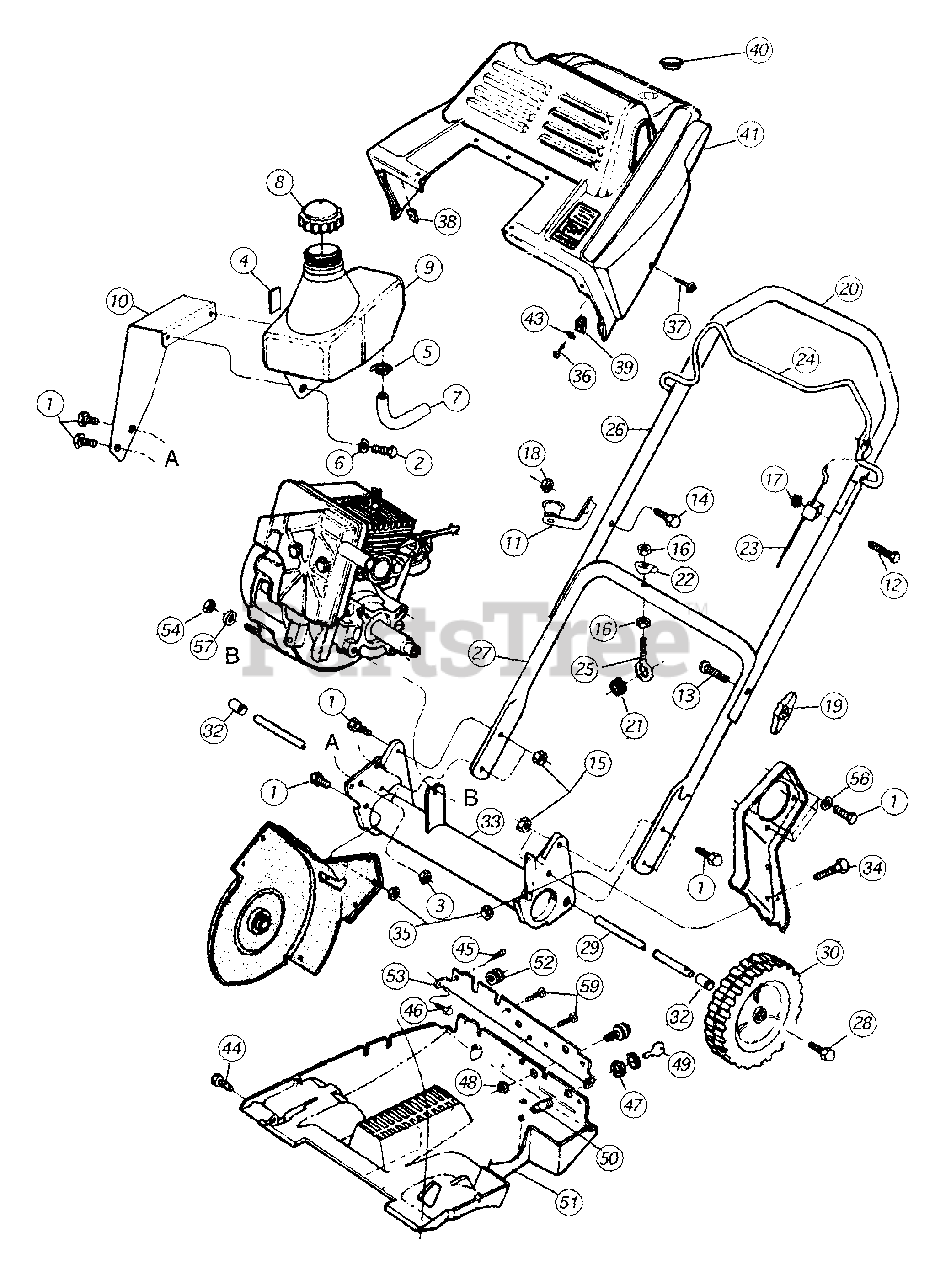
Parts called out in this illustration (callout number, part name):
1	Hex Screw: 5/16 - 18 x .75 Gr 2
2	Hex Screw: 1/4 - 14 x .625
3	Nylock Nut
4	Foam Strip
5	Hose Clamp 1/2" OD
6	Flat Washer
7	Hose, Fuel Line
8	Fuel Tank Cap
9	Fuel Tank
10	Support Bracket
11	Bracket Assembly, Rope Guide
12	Hex Screw: 1/4 - 20 x 2.0 Gr 5
13	Carriage Bolt: 5/16 - 18 x 2.0 Lg. Carved
14	Oval C-Sunk Screw
15	Nylock Nut
16	Hex Nut: 5/16 - 18
17	Top Lock Nut Nylon Insert
18	Top Lock Nut 1/4 - 20
19	Knob Assembly
20	Foam Grip, Handle
21	Grommet: .44 ID x .94 OD x .50
22	Side Lock Washer
23	Drive Cable, Auger
24	Auger Bail, Drive Dipped
25	Eye Bolt 5/16 - 18
29	Axle, Tube
30	Wheel Assembly
32	Spacer
35	Nylock Nut
36	Hex Screw
37	Ab Screw
38	Retainer Clip, U-Style
39	U Nut
40	Snap-In Plug
41	Upper Engine Cover
43	Flat Washer
44	Hex Screw: 1/4 - 20 x .625
45	Tap Screw: 10 - 24 x .75
46	Tap Screw: 10 - 25 x .75
47	Jam Nut: 5/8 - 32 x .12
48	Top Lock Nut Nylon insert
49	Ignition Key
50	Recoil Starter Key
51	Lower Engine Cover
52	Grommet: .280 x .750 x .40
53	Control Panel
54	Nylock Nut
56	Lock Washer
57	Flat Washer
59	Cord Assembly
